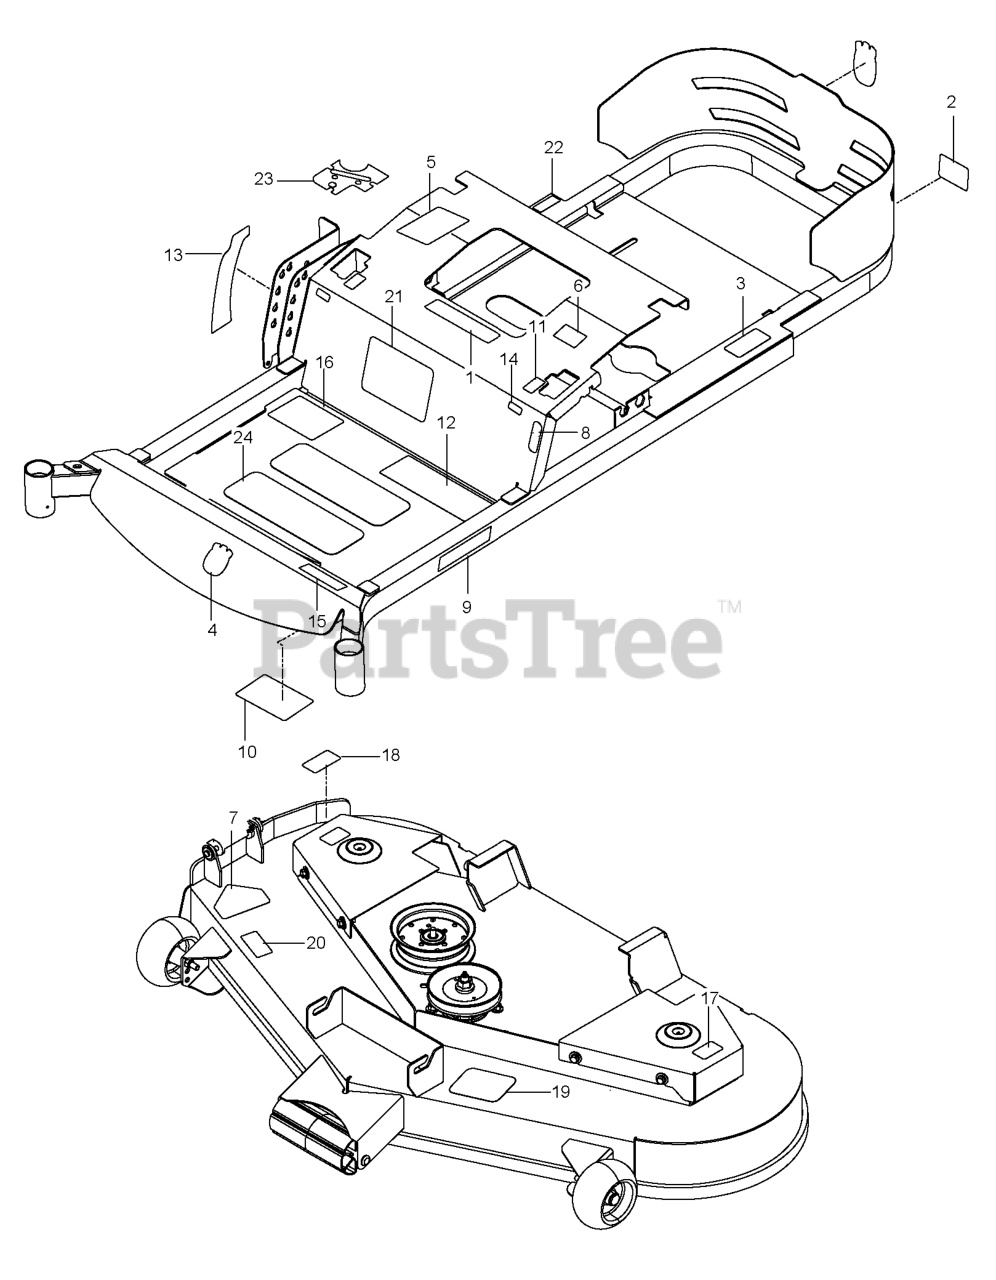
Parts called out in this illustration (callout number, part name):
1	EURO DECAL-BATTERY WARNIN6
2	DECAL, PROP. 65
3	DECAL, DO NOT TOW
4	DECAL.AUGER.HUSQ.CROWN.SNOW
5	DECAL, CUSTOMER RESPNSIBILITY
6	DECAL, EXITING MOWER
7	DECAL, CPSC
8	DECAL, PARK BRAKE
9	RP.DECAL.BADGE.170MM.TEXTLOGO
10	DECAL, SERVICE
11	DECAL, MOTION CONTROL
12	DECAL, SAFETY WARNING
13	DECAL, DECK HEIGHT, HUSQ
14	DECAL, F.S.T.
15	DECAL, EZ4824
16	DECAL, WARNING
17	DECAL, NO STEP
18	DECAL, CAUTION
19	DECAL, BELT ROUTING
20	DECAL, EURO SEVERING
21	DECAL, START
22	DECAL, WARNING SPARK ARRESTOR
23	DECAL, CTRL PANEL, HUSQ
24	ANTI-SKID PAD
